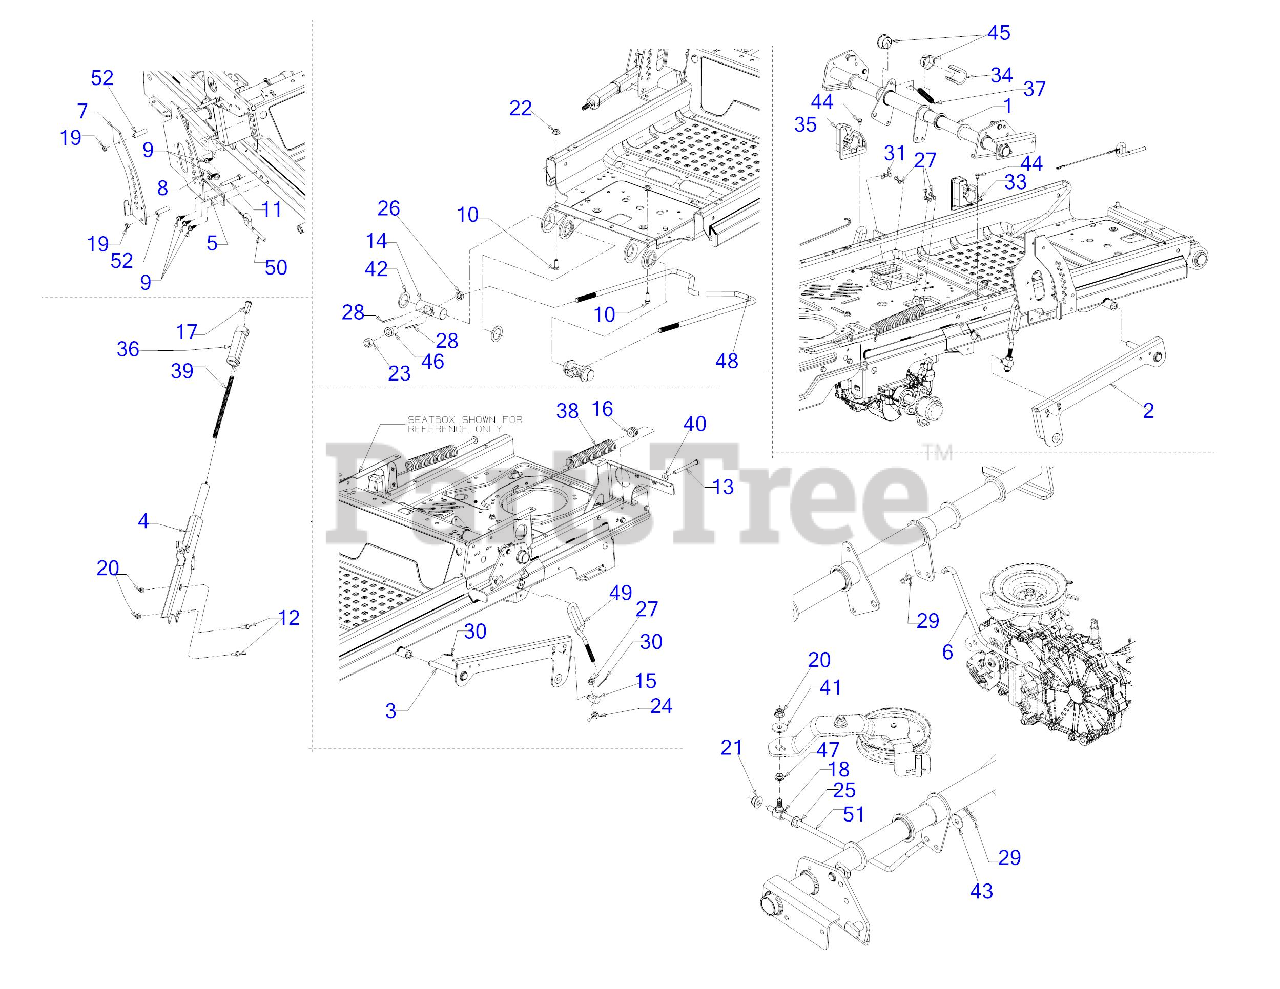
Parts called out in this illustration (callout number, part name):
4	LATCH HANDLE ASSEMBLY
6	BRAKE ROD ASSEMBLY
8	HEX SCREW AB-TAP #10-16 x 0.500
9	SCREW 5/16-18 x .750
10	SCREW 3/8-16 x 1 GR5
11	HEX SCREW-3/8-16X2.5 GR5
12	SCREW 5/16-18 x .75 GR5
13	SCREW 3/8-16X4.25 GR5
15	LIFT LINK FERRULE
16	SPRING INSERT
17	LIFT HANDLE BUTTON
18	FERRULE 3/8 X 0.375
19	JAM LOCK NUT
20	FLANGE LOCK NUT 5/16-18
22	FLANGE LOCK NUT
24	HEX NUT NYLOK 1/2-13
25	HEX FLANGE NUT
26	HEX NUT
27	HEX NUT
28	COTTER PIN
29	BOW TIE COTTER PIN 1/4-5/16
30	COTTER PIN
31	BOW TIE COTTER PIN
33	DECK LIFT BRACKET
34	SPACER-1.375 SHAFT
35	DECK LIFT BRACKET (LH)
36	LIFT HANDLE GRIP
37	EXTENSION SPRING .63 x 4.95
38	EXTENSION SPRING 1.485 OD x 17.58
39	COMPRESSION SPRING
40	FLAT WASHER .385X.870X.090
41	FLAT WASHER 1.0 OD:.331 ID
42	FLAT WASHER
43	FLAT WASHER 344X1.00
44	SHOULDER SCREW 1/4-20X.50 19"PSH
45	FLANGE BEARING
46	FLANGE BEARING
47	FLANGE BEARING
48	DECK FRONT HANGER ROD
49	LIFT ADJUSTMENT LINK
51	BRAKE DISENGAGEMENT ROD
